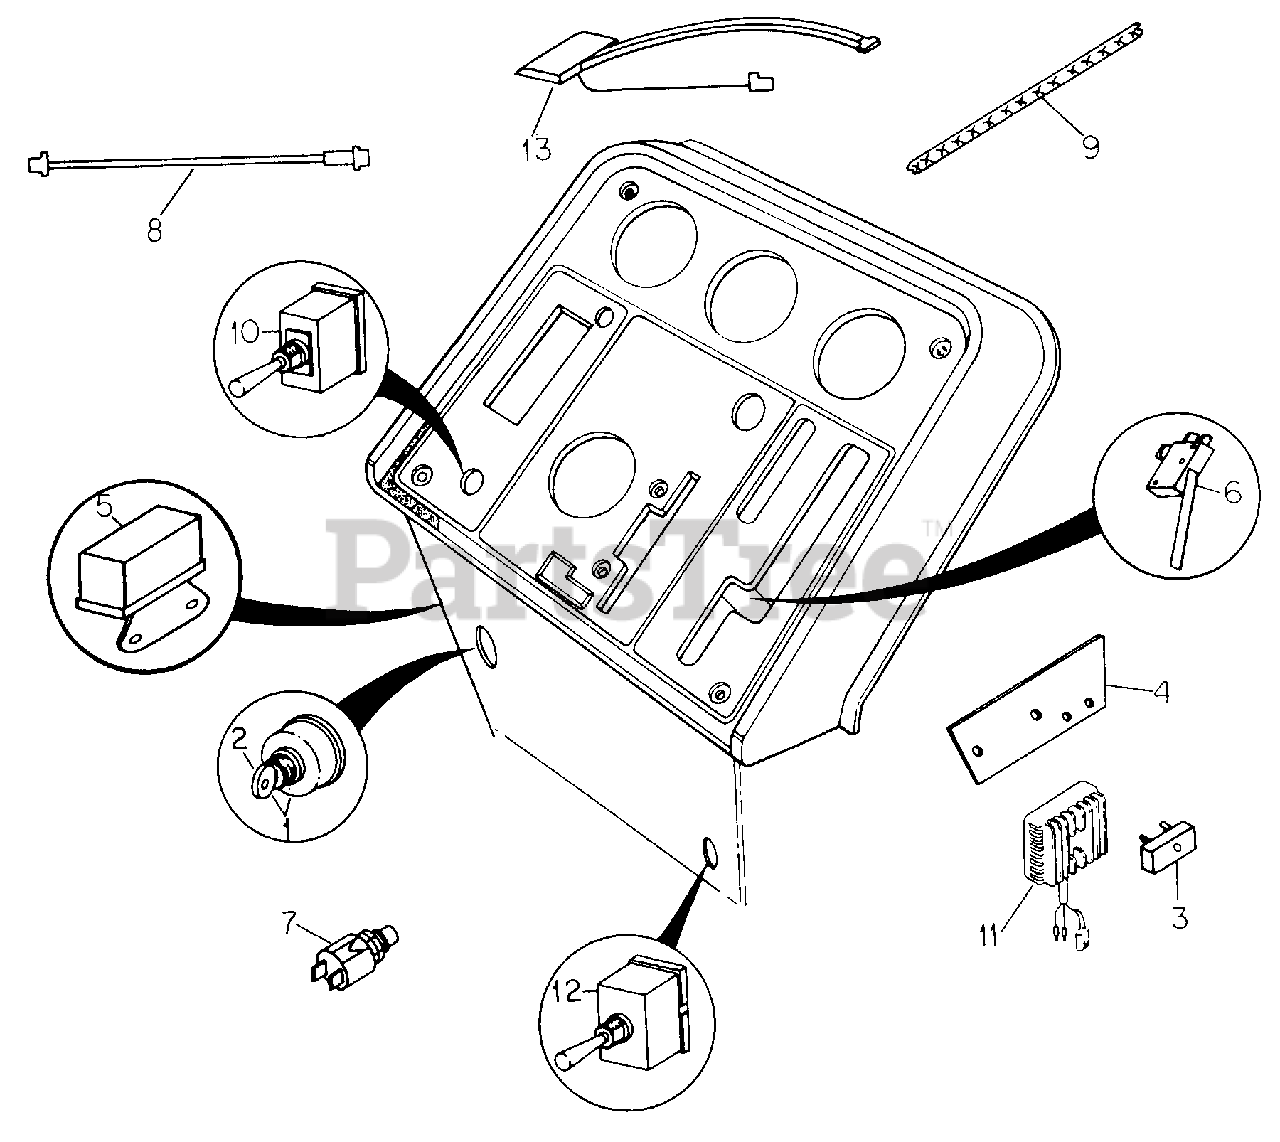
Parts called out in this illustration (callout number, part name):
1	Switch, Ignition
2	Key, Ignition (Set of 2)
3	Breaker, Circuit
4	Bracket, Circuit Breaker
5	Relay
6	Switch, Reverse Cut-Out
7	Switch, Neutral Start
8	Cable, Seat Switch Extension
9	Harness Assy, Main Cable
10	Switch, PTO
11	Regulator
12	Switch, Light
13	Switch, Seat
